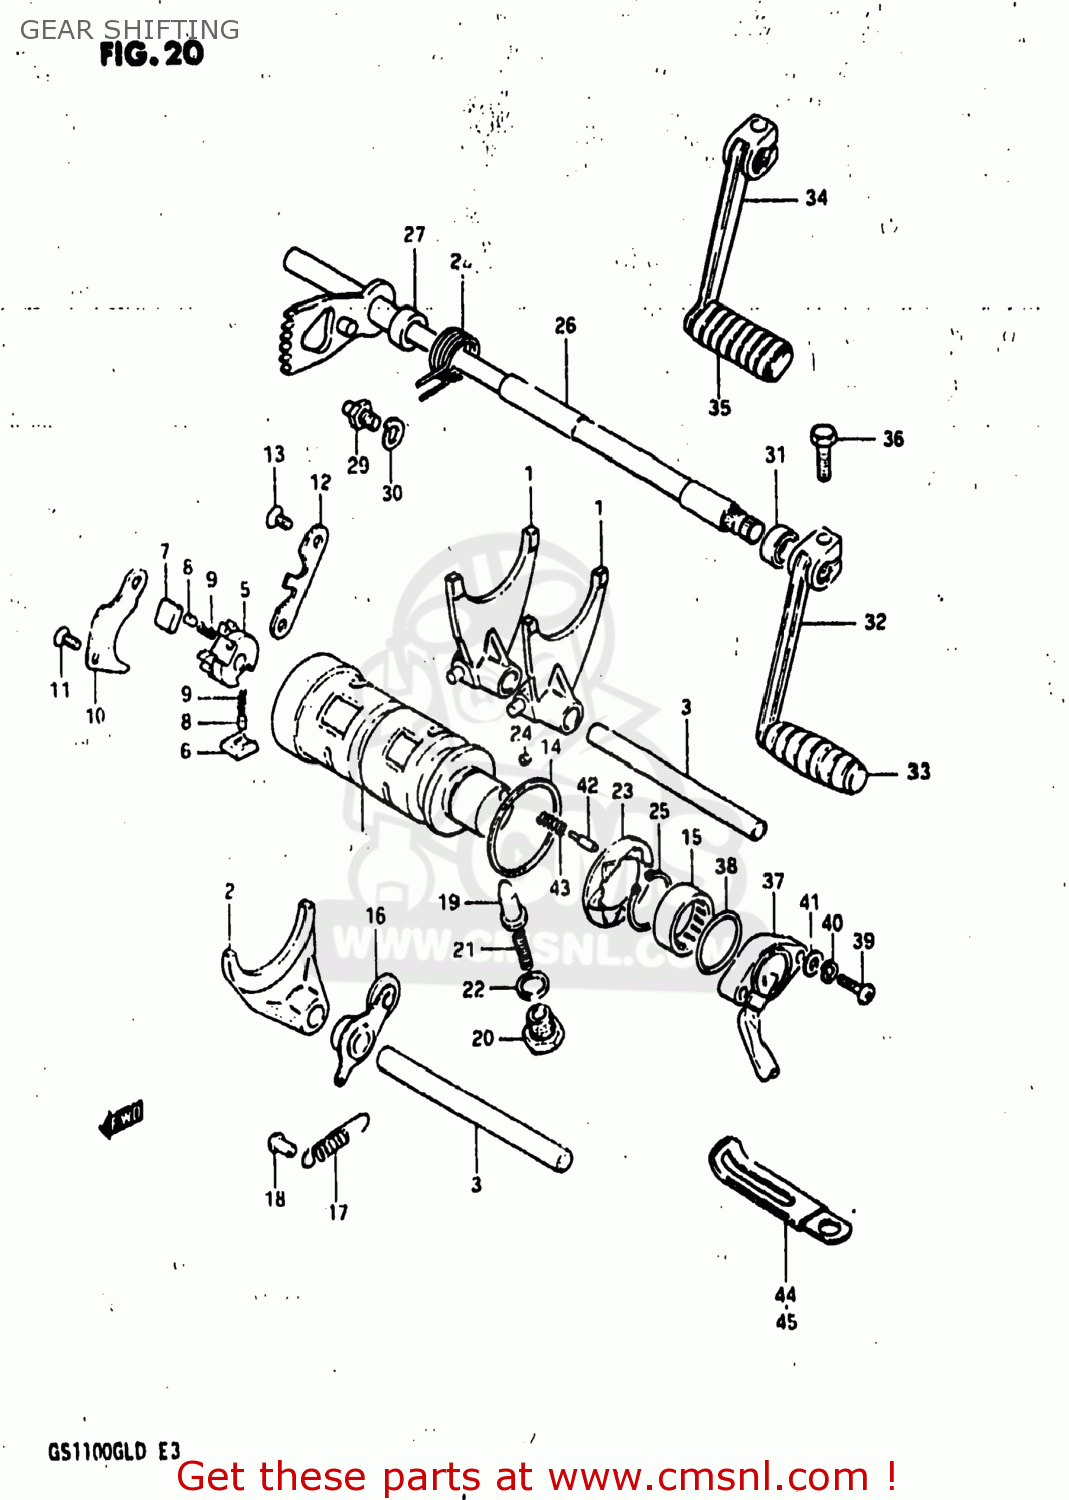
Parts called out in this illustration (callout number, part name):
1	FORK,GEAR SHIFT NO.1
2	FORK,GEAR SHIFT NO.3
3	SHAFT,GEAR SHIFT FORK
4	CAM,GEAR SHIFT
5	RETAINER,GEAR SHIFT CAM
6	PAWL,GEAR SHIFT NO.1
7	PAWL,GEAR SHIFT NO.2
8	PIN(5X8)
9	SPRING
10	LIFTER,GEAR SHIFT PAWL
11	SCREW
12	GUIDE,GEAR SHIFT CAM
13	SCREW
14	WASHER(40X45X1)
15	BEARING
16	STOPPER,GEAR SHIFTING
17	SPRING
18	RIVET
19	STOPPER,GEAR SHIFT CAM NO.2
20	HOLDER,GEAR SHIFT CAM STOP SPR
21	SPRING
22	GASKET(14X19.2X2) (NAS)
23	PLATE,GEAR SHIFT CAM STOPPER
24	PIN 4X6
25	CIRCLIP,25MM
26	SHAFT,GEAR SHIFT
27	SPACER (12X20X12)
28	SPRING
29	STOPPER,GEAR SHIFT CAM
30	WASHER
31	OIL SEAL
32	LEVER ASSEMBLY,GEAR SHIFTING
33	RUBBER,GEAR SHIFT PEDAL
34	LEVER ASSY,GEAR SHIFT
35	RUBBER,PEDAL
36	BOLT
37	TERMINAL BASE ASSY,GEAR SHIFT
38	O-RING (D:2.4 ID:26.2)
39	SCREW 5X20
40	LOCK WASHER
41	WASHER
42	PIN(5X15.5)
43	SPRING
44	CLAMP L:35
45	CLAMP
